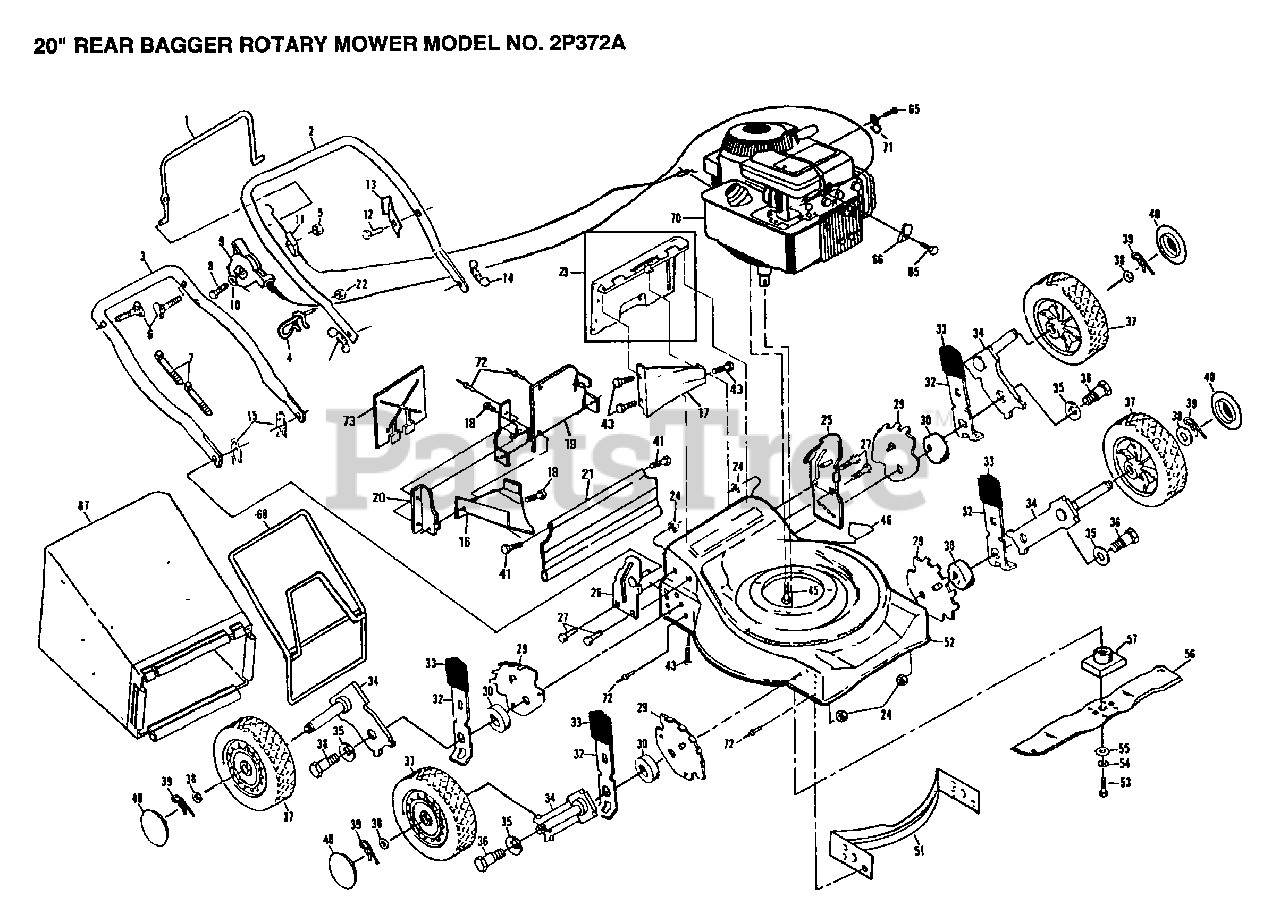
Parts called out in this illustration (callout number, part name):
1	CONTROL BAR
4	ROPE GUIDE
6	BOLT.HANDLE.LM
9	CONTROL THROTTLE
10	WASHER PM
11	"CABLE,ENG ZONE CO"
12	TAPPING SCREW
13	"BRKT,UPSTOP"
14	"NUT,WING PM"
15	HAIRPIN COTTER
16	DISCHARGE GUARD
17	REAR BAFFLE
18	SCREW PM
19	PLATE.BACK.20RD
22	NUT
23	"KIT, REAR DOOR PM"
24	LOCKNUT PM
27	SCREW
32	SPRING SELECTOR
33	KNOB PM
34	AXLE ARM
35	"WASHER, BELLEVIL."
38	WASHER
39	RETAINER CLIP PM
40	HUB CAP
41	HINGE SCREW
43	SCREW
45	SCREW
46	DECAL HYT
52	KIT.HSG.20RD
53	SCREW
54	LOCKWASHER
55	"WASHER,HARDEN"
57	BLADE ADAPTOR
65	SCREW PM
66	CABLE CLAMP
67	GRASS BAG
68	CATCHER FRAME
71	GUIDE CLIP PM
72	BLIND RIVET
73	MULCHER PLATE
